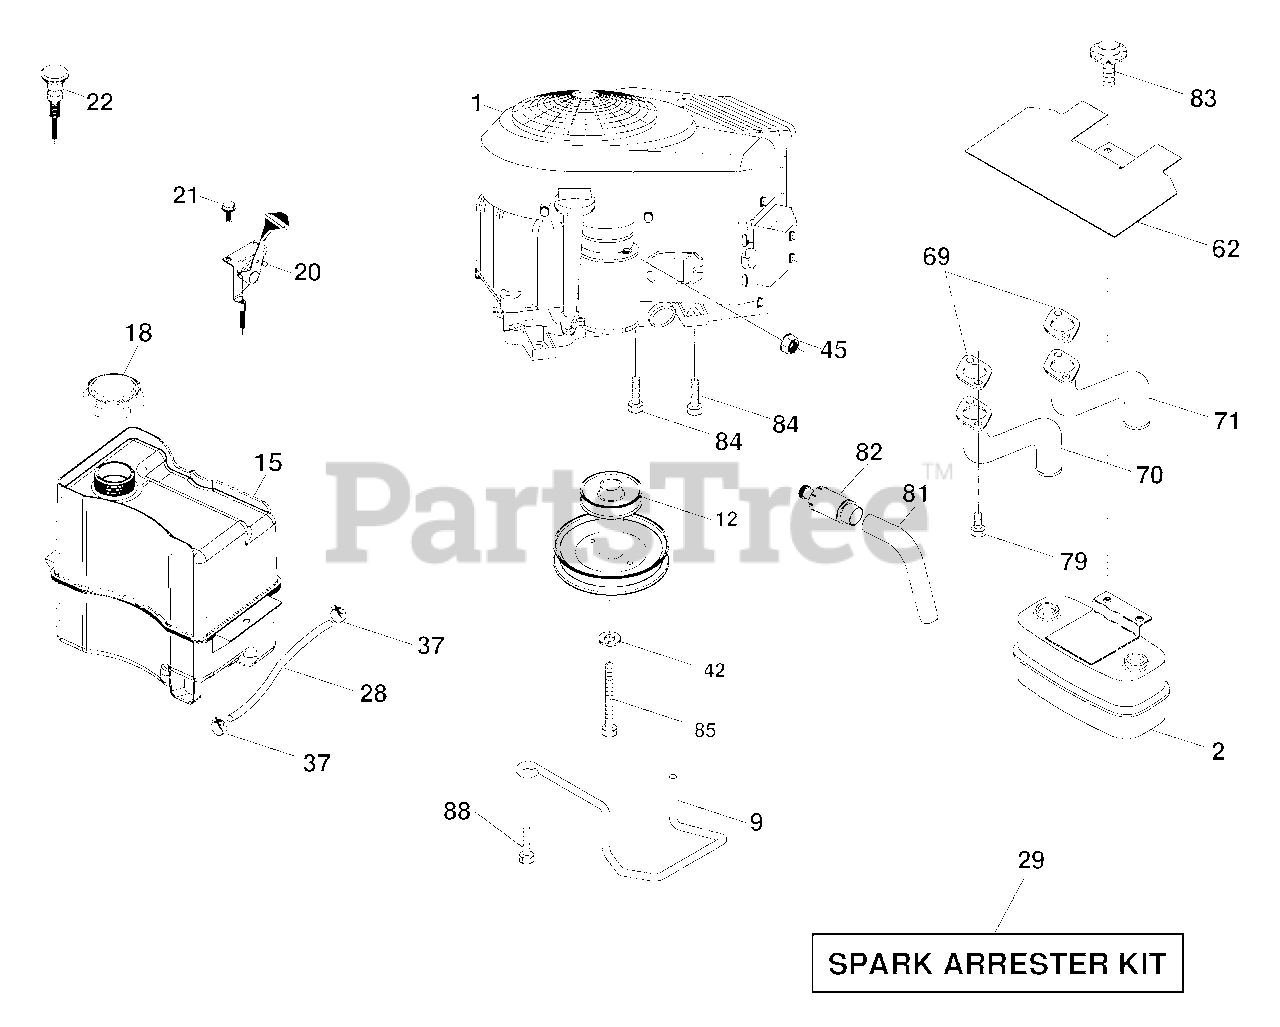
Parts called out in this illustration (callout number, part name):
2	Muffler
9	Keeper Belt Engine
12	Pulley Engine
15	Tank Fuel
18	Cap Asm
20	Control Throttle
21	Screw 10 x 3/4 Single Lead-Hex
22	Control Choke
28	Fuel Line
29	Spark Arrester Kit
35	Washer Split
37	Clamp Hose
42	Washer Lock 7/16
45	Nut Keps Hex 1/4-20 unc
62	Shield Heat Muffler
69	Gasket
70	Exhaust Tube LH
71	Exhaust Tube RH
79	Screw Socket Head 5/16-18 x .75
81	Tube Drain Oil Easy
82	Plug Drain Oil
83	Bolt 5/16-18 x 3/4
84	Screw 3/8-16 x 1-1/4
85	Bolt Hex 7/16-20 x 4 x Gr. 5-1.5
88	Screw 3/8-16 x 1
